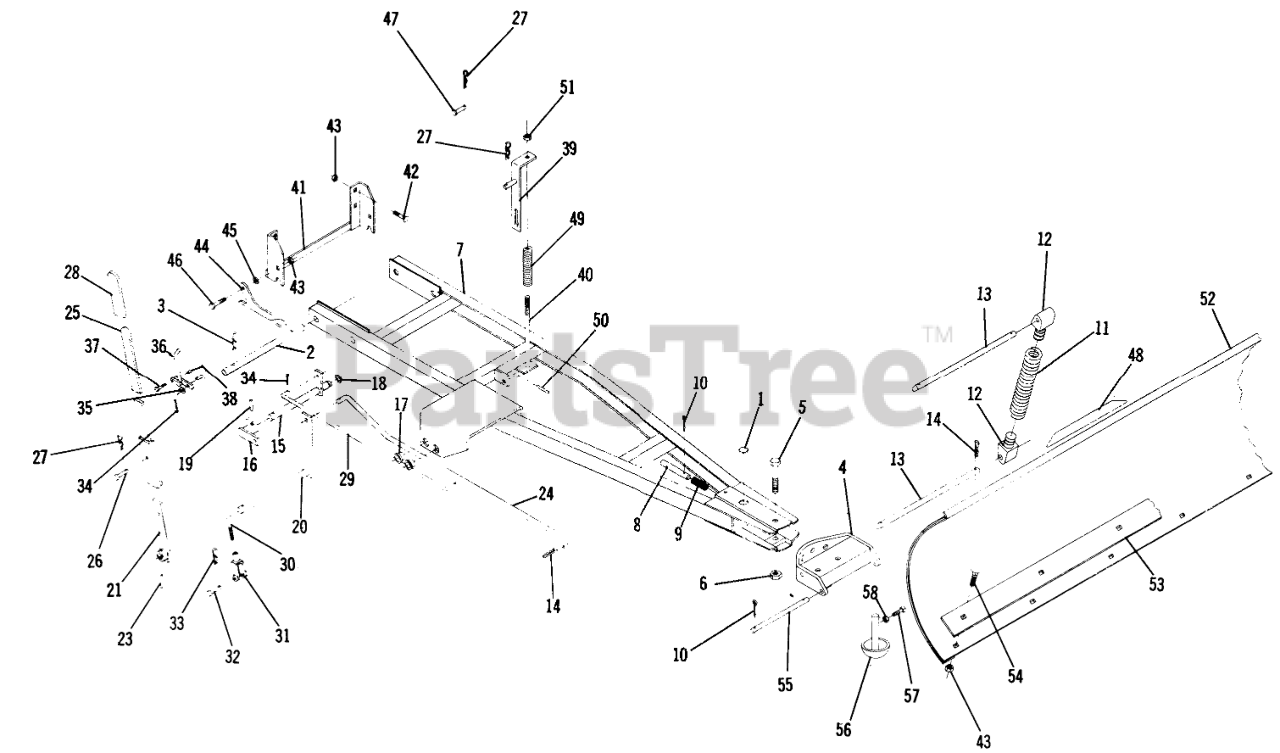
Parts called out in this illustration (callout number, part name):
1	PLUG
2	Mounting Shaft
3	Hairpen
4	Sector and Channel
5	Bolt Hex 3/4-16 x 3 3/4
6	Nut-3/4-16 E.S.
7	Frame Assembly
8	Index Pin
9	SPRING-COMPRESSION
10	Cotter Pin
11	Spring
12	Lug
13	ROD-TRIP RETURN
14	Hairpin
15	Bushing
16	Sat Collar
17	BUSHING
18	Snap Ring
19	SPIROL PIN 3/8X1 3/4
20	Assembly-Blade Index Arm
21	Assembly-Handle Bar
22	3/8-16 Jam Nut
23	SPIROL PIN 3/8X1 1/2
24	Blade Control Rod
25	HANDLE ASM
26	Clevis Pin
27	Hairpin
28	GRIP
29	ROD LOWER INDEX
30	ROD UPPER INDEX
33	Hairpin
34	Cotter Pin
35	Washer
36	Assembly Index Lever
37	Bolt-Hex 1/4-20
38	Nut-Nylok
39	Assembly-Lift Bar
40	Assembly Lift Rod
41	Breather
42	Bolt-Carr. 3/8-16 x 3 1/2
43	3/8-16 E.S.
44	Latch Hitch
45	Washer
46	Bolt, 3/8-16 x 1 1/2
47	Pin Clevis
48	DECAL-WHEEL HORSE
49	SPRING
50	Spirol Pin
51	Nut-ES 1/2-13
52	Assembly Blade-54"
52	Blade Assembly
53	Plate-Blade Edge
53	PLATE-BLADE EDGE
54	Bolt-3/8-16 x 3/4
55	ROD-LOWER
56	Skid
57	Set Screw-3/8-16 x 1
